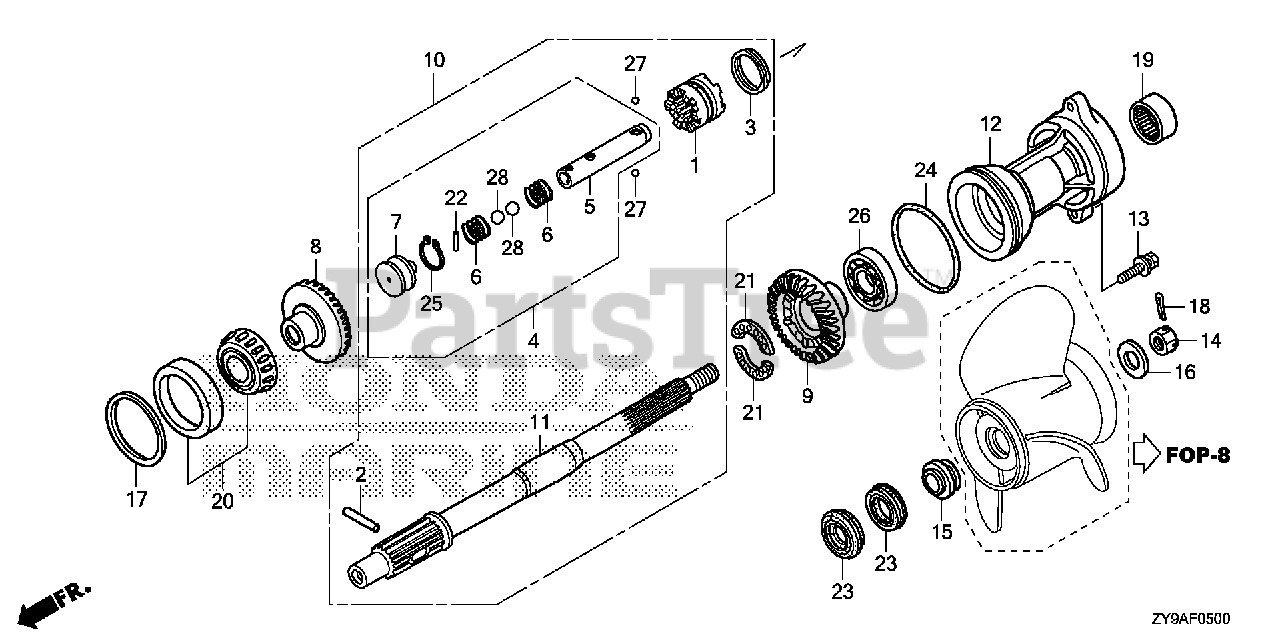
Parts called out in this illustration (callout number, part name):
1	SHIFTER, CLUTCH
2	PIN, SHIFTER (8X47)
3	RING, CROSS PIN
4	SLIDER, SHIFT
5	SLIDER, SHIFT
6	SPRING, SHIFT
7	PLATE, SHIFT
8	GEAR, FR. BEVEL
9	GEAR, RR. BEVEL
10	SHAFT ASSY., PROPELLER
11	SHAFT, PROPELLER
12	HOLDER, PROPELLER SHAFT *NHB14M* (AQUA MARINE SILVER METALLIC)
13	BOLT-WASHER (10X40)
14	NUT, CASTLE (18MM)
15	WASHER, PROPELLER THRUST
16	WASHER, PLAIN (18.5MM)
17	SHIM A, BEVEL (0.10) (FR)
17	SHIM B, BEVEL (0.15) (FR)
17	SHIM C, BEVEL (0.30) (FR)
17	SHIM D, BEVEL (0.50) (FR)
18	PIN, SPLIT (4.0)
19	BEARING, NEEDLE (30X37X26)
20	BEARING, TAPERED ROLLER (50X82X21.5)
21	BEARING, BALL (28X38X3)
22	ROLLER (3X12.8)
23	SEAL, WATER (30X45X7)
24	O-RING (94X4.1)
25	CIRCLIP, OUTER (14MM)
26	BEARING, RADIAL BALL (6208)
27	BALL, STEEL (#7) (7/32)
28	BALL, STEEL (#11) (11/32)
